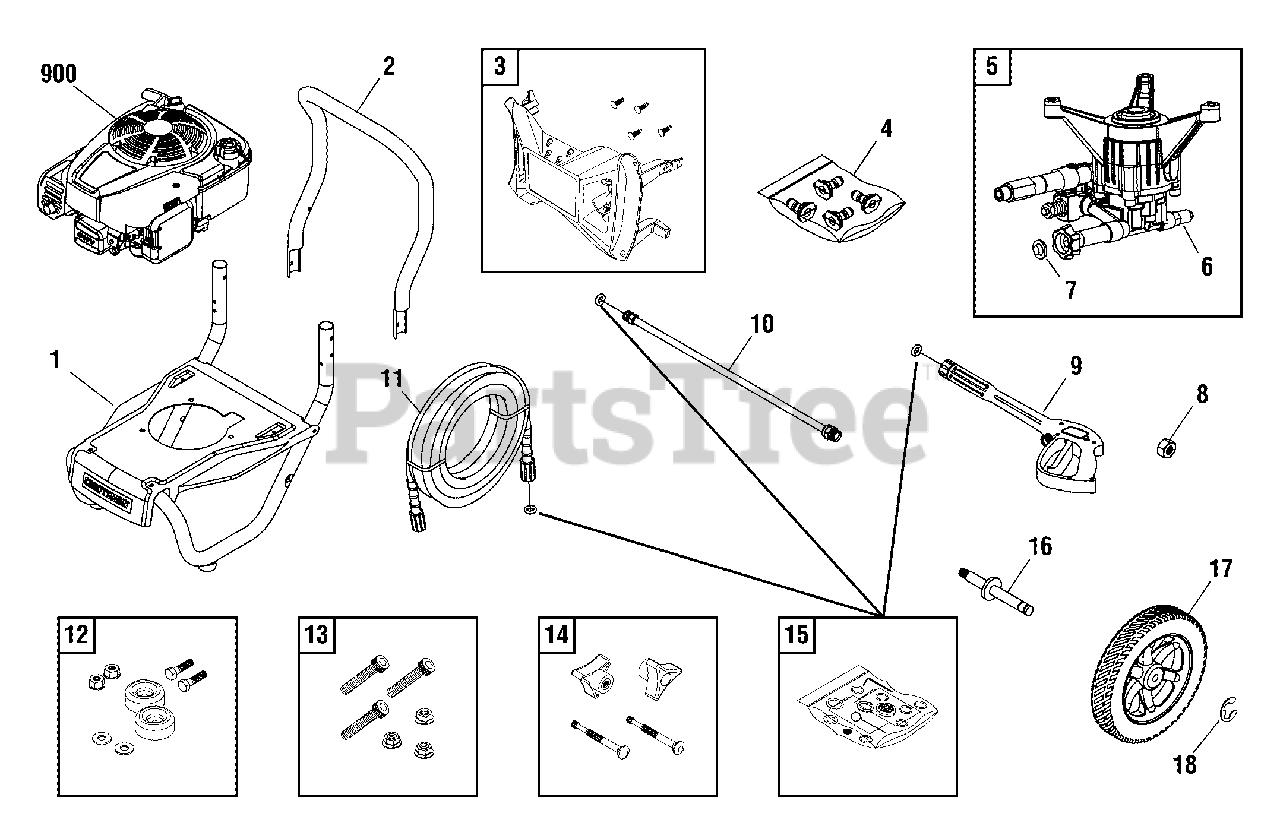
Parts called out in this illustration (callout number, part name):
4	KIT, QC Nozzles
6	VALVE, Thermal Relief
7	FILTER, Garden Hose
9	GUN
10	EXTENSION, QC
11	HOSE
12	MOUNT, Vibration
13	KIT, Hardware, Pump Mounting
14	KIT, Hardware, Handle
15	KIT, O-Rings
18	E-RING
900	** ENGINE
